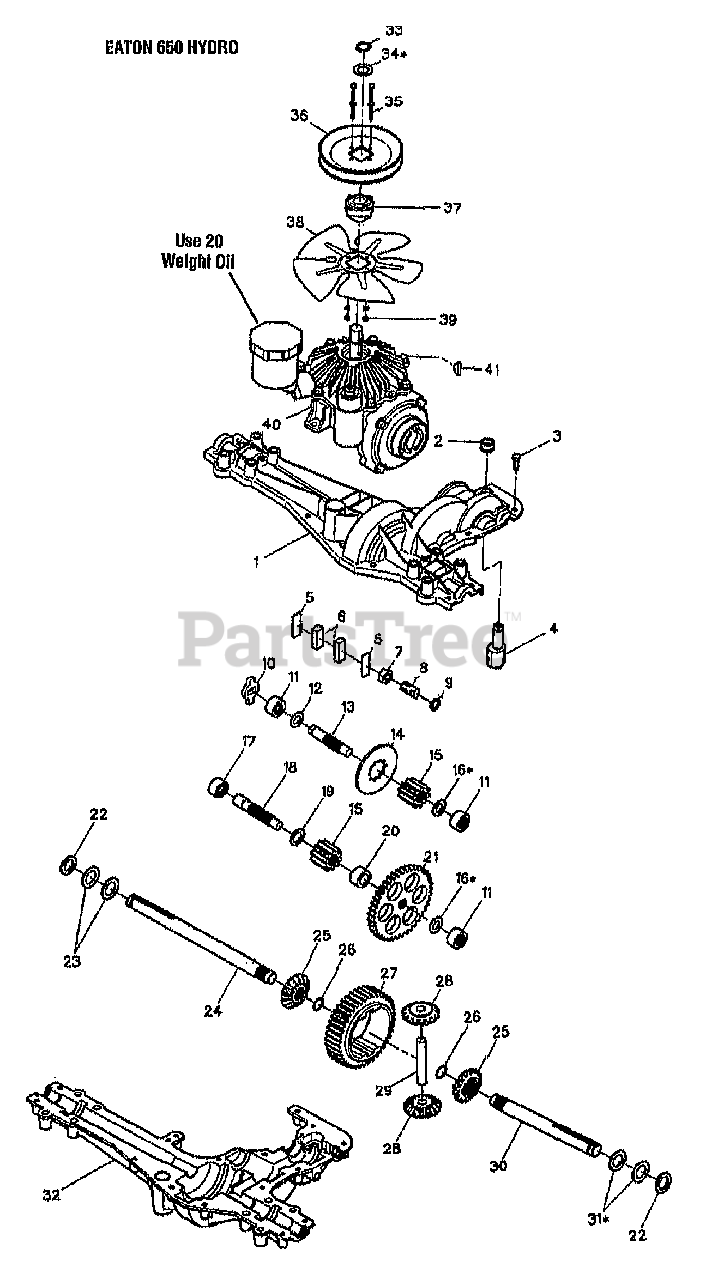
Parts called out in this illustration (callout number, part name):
1	HOUSING-UPPER
2	RING-V
3	SCR-SELF TAP 1/4-20X.734
4	ASSM-SHAFT & CAM
5	SPACER
6	BLOCK FRICTION
7	NUT-HEX/JAM
8	ADJUSTMENT-STUD
9	RING-O
10	KEY-DRIVE
11	ASSM-BEARING
12	WASHER-.505 X .942 X .040
13	SHAFT-INPUT
14	BRAKE-DISC
15	SPUR-GEAR 10T
16	KIT-SHIM (.500 SHAFT)
17	ASSM-BEARING
18	SHAFT-IDLER
19	WASHER-.632 X 1.0 X .041
20	SPACER .630 X 1.00 X .549
21	SPUR-GEAR 41T
22	WASHER-NEOPRENE
23	WASHER-.758X1.25X.031
24	AXLE-TRANSMISSION LH
25	MITER-GEAR 15T
26	RING-RETAINING
27	SPUR-GEAR 41T
28	MITER-GEAR 15T
29	SHAFT-CROSS
30	AXLE-TRANSMISSION RH
31	KIT-SHIM (.750 SHAFT)
32	HSG-TRANSMISSION LOWER
33	RING-RETAINING
34	KIT-SHIM (.670 SHAFT)
35	SCR-HHC #6-32X.88
36	PULLEY-4.50" DIA
37	HUB-PULLEY
38	KIT-FAN
39	NUT-H/LK #6-32
40	ASSM-HYDROSTATIC
41	KEY-WOODRUFF
